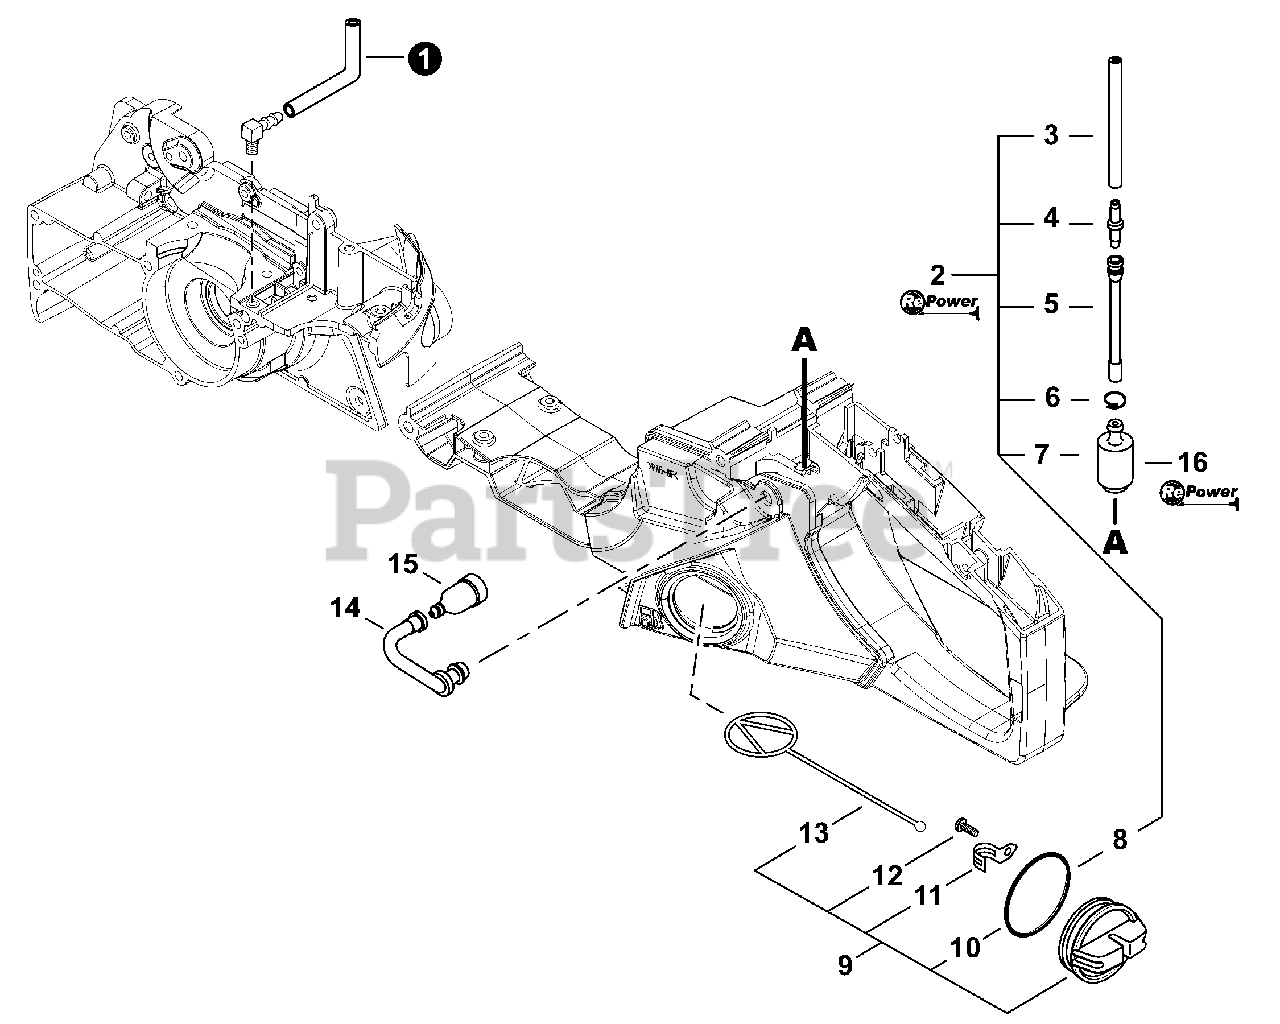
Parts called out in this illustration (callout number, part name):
1	PIPE, PULSE
2	FUEL SYSTEM KIT
3	PIPE, FUEL 3×6×75
4	CONNECTOR, PIPE
5	PIPE, FUEL
6	CLIP Ø6
7	FILTER, FUEL
8	O-RING 29
9	CAP ASSY, FUEL
10	O-RING 29
11	RETAINER, CONNECTOR
12	SCREW, TAPPING 3×8
13	CONNECTOR, CAP L= 60 MM
14	PIPE, FUEL VENT
15	VENT ASSY
16	TUNE-UP KIT - REPOWER
